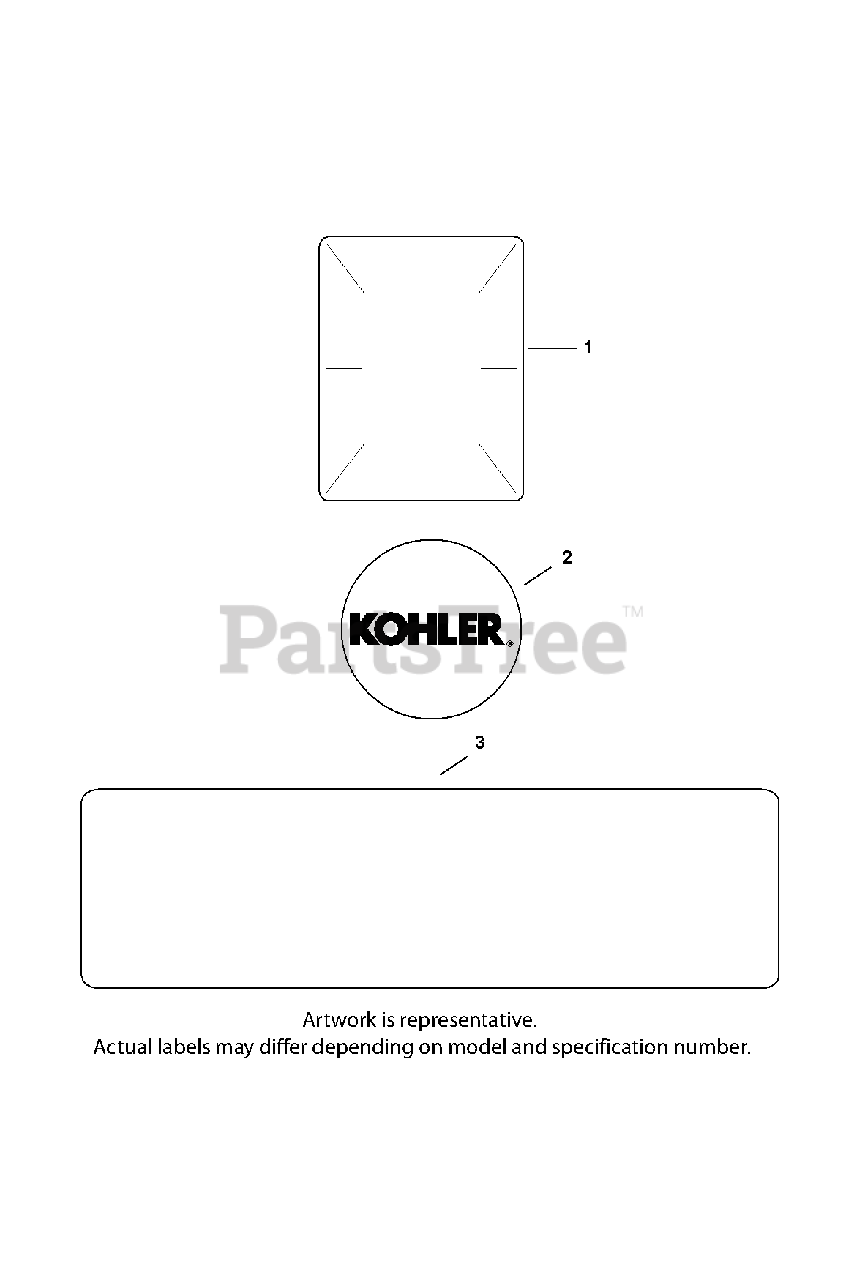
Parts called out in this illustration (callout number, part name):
1	Decal, Clear Laminate
2	Decal, Grass Screen
3	Decal, Command 25 HP
